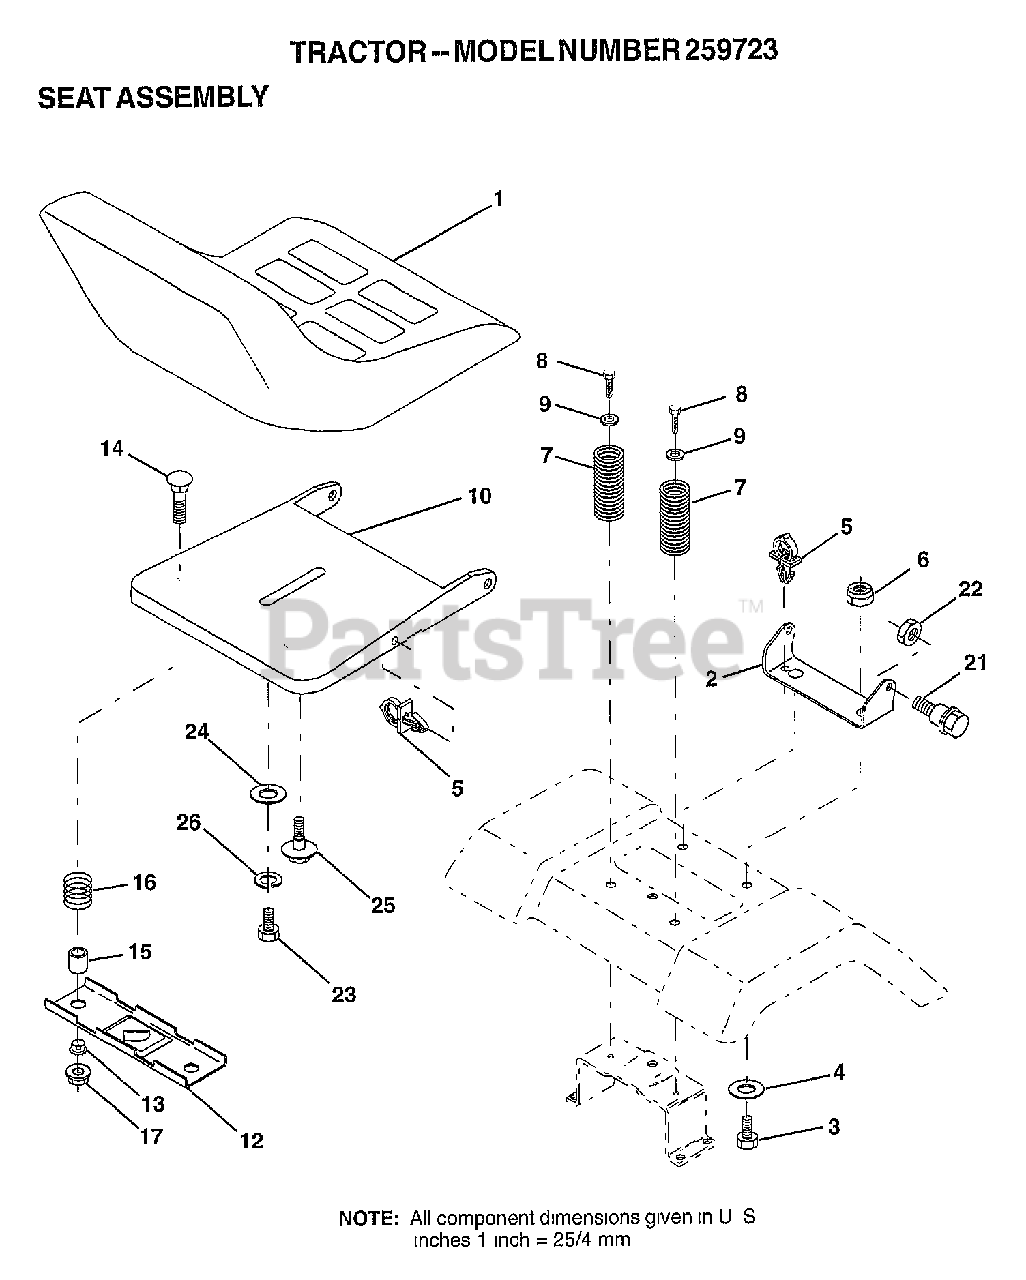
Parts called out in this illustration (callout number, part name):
2	BRACKET PVT SEAT
3	BOLT
4	WASHER PM
5	CLIP.PUSH-IN.HING
6	NUT
7	SPRING COMPRESSIO
8	SCREW
9	WASHER
10	PAN-SEAT
12	BRKT SWITCH
13	BUSHING
14	BOLT-RD HD SQ NK
15	SPLIT SPACER
16	SPRING
21	BOLT
22	NUT
23	BOLT
24	WASHER
26	LOCKWASHER
